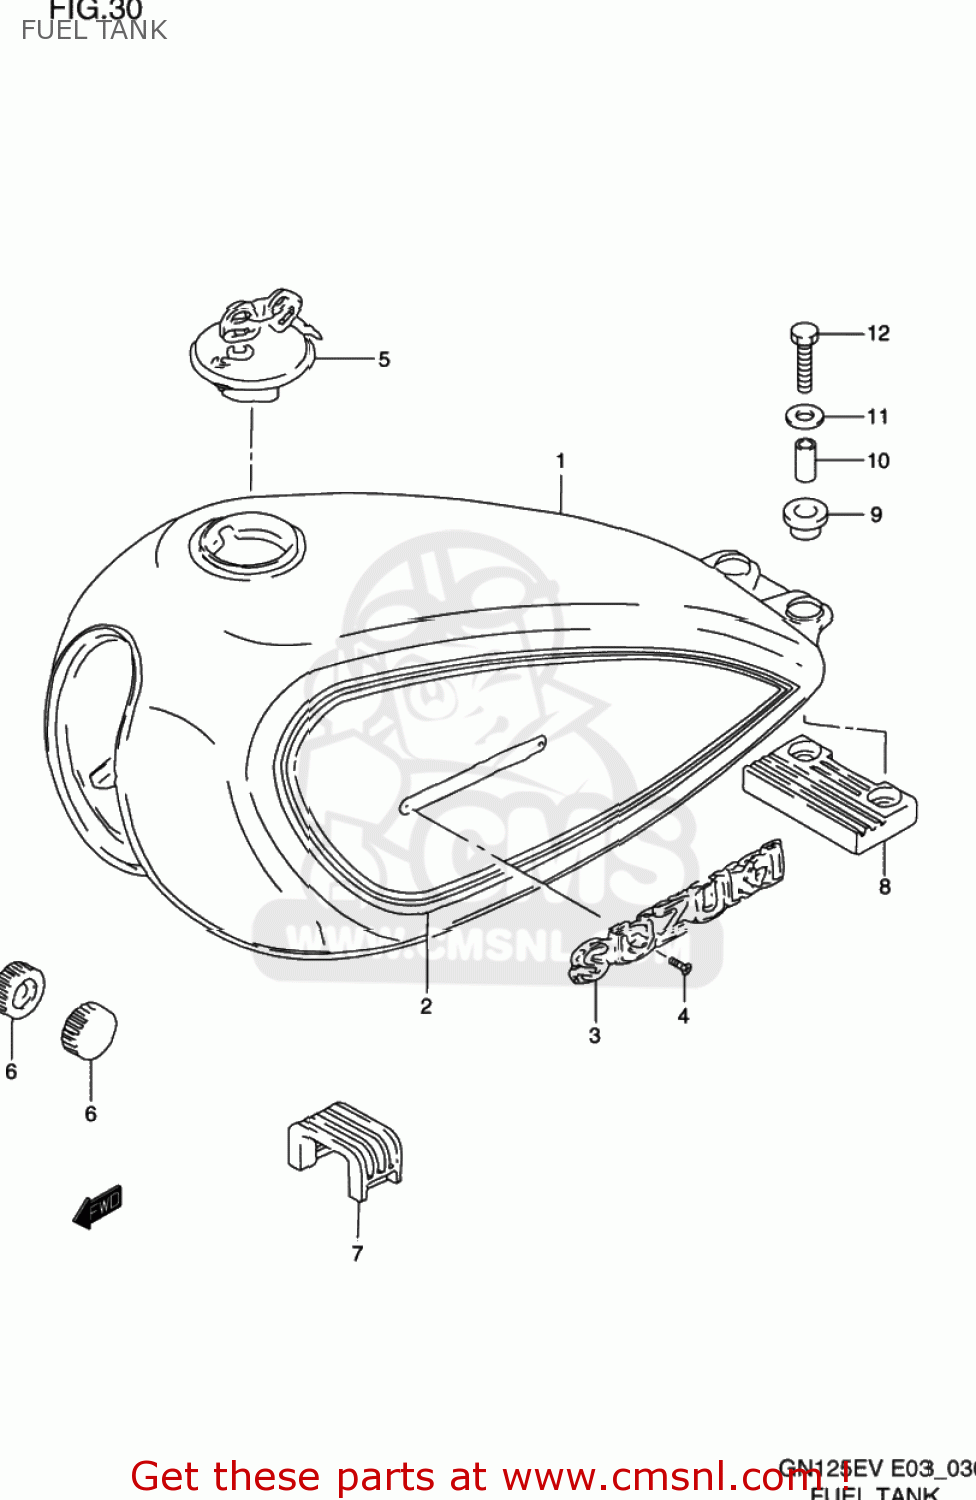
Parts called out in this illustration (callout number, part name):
1	TANK ASSEMBLY,FUEL (RED)
2	TAPE SET,FUEL TANK
3	EMBLEM,FUEL TANK
4	SCREW
5	CAP SET,FUEL TANK
6	CUSHION
7	CUSHION,FUEL TANK UPR FR
8	CUSHION,TANK RR NO.1
9	CUSHION
10	SPACER(6.5X10.5X22.5)
11	WASHER(6.5X22X1.6)
12	BOLT(6X35)
